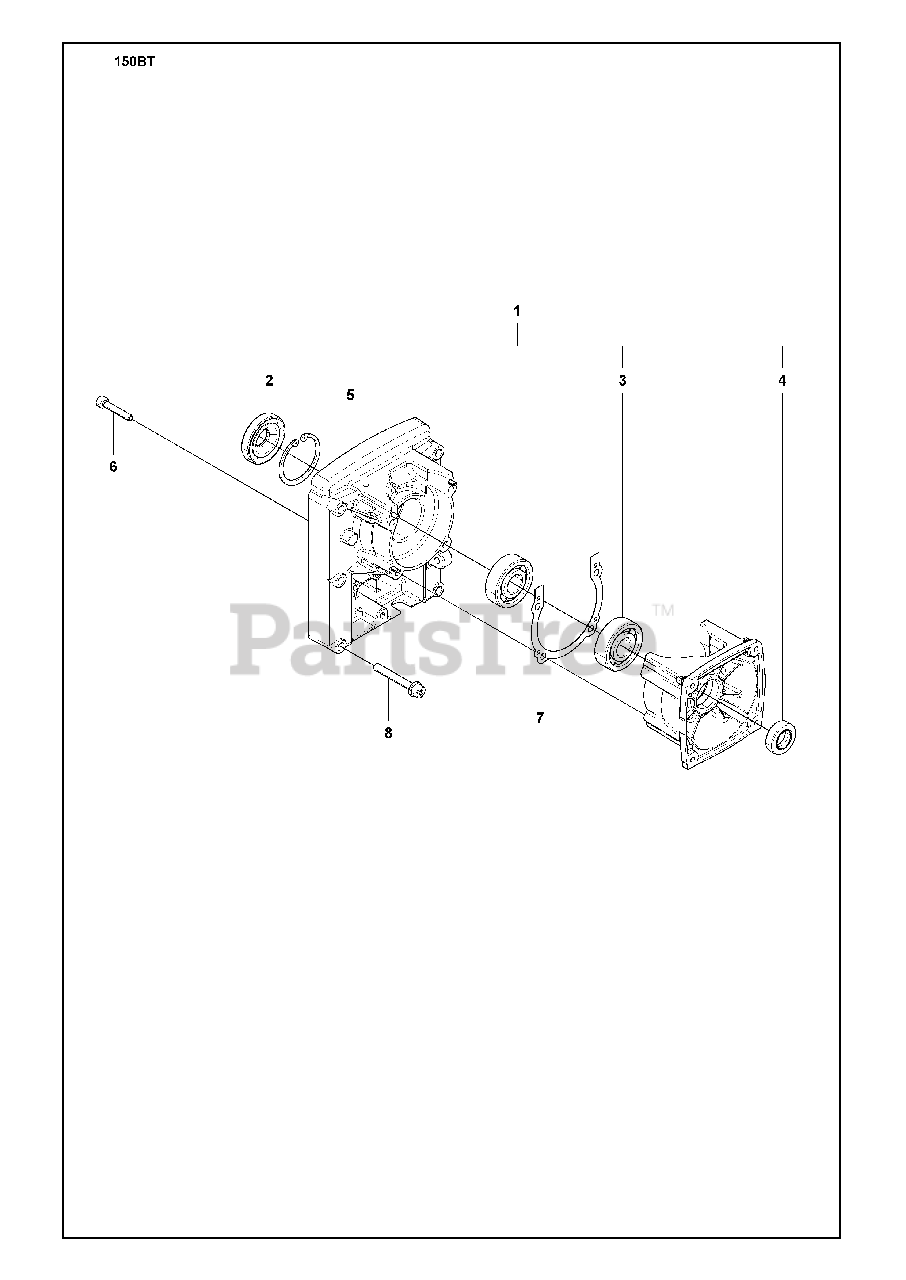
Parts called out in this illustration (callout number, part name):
3	BEARING
6	BOLT
8	BOLT
